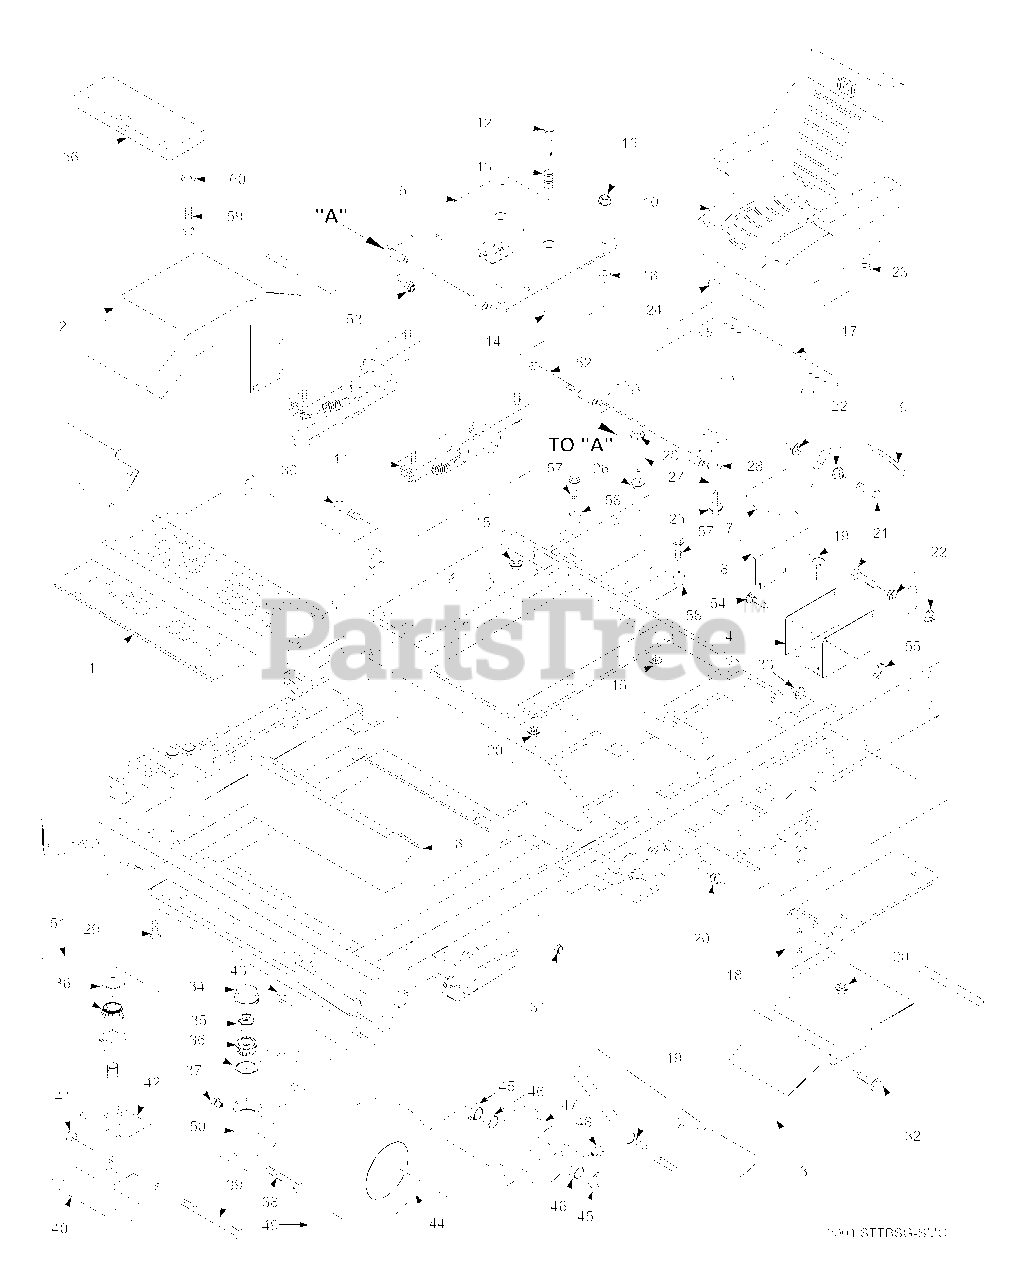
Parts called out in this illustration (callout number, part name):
1	Footplate
2	Fender, RH
3	Fender, LH
4	Box, Battery
5	Plate, Lower Seat
6	Footrest
7	Insulation, Battery Cover
8	Cover, Battery
9	Cable, Seat Stop
10	Seat
11	Track Set, Seat Adjuster
12	Pin, Spring
13	Spring, Seat
14	Spring Pin, .156 x .75"
15	Nut, Serr. Flg. 5/16-18
16	Spacer
17	Plate, Upper Seat
18	Bracket, Battery
19	Bolt, Carr. 5/16 -18 x .75"
20	Nut, Serr. Flg. 5/16-18
21	Bolt, Hex Head 1/4-20 x 1.25"
22	Nut, 1/4-20
23	Spacer
24	Spacer
25	Bolt, Hex Head 5/16-18 x 1.5"
26	Bolt, Hex Head 5/16-18 x 2.25"
27	Lock Washer 5/16"
28	Flat Washer 5/16 .375 x .875 x .083
29	Bolt, Hex Head 1/2-13 x 1.5"
30	Bolt, Hex Head 3/8-16 x 1.0"
31	Nut, Elastic Stop 3/8-16
32	Capscrew, Serr. Flng. 3/8-16 x 1.00"
33	Nut, Serr. Flng. 3/8-16
34	Cap, Grease
35	Nut, Hex Elastic Stop 1.0-14
36	Bearing w/ Race
37	Plug, 1/4-28 THD Form
38	Bolt, Hex Head 5/8-11 x 4.00"
39	Bolt, Hex Head 1/2-13 x 7.5"
40	Spacer
41	Nut, Hex Head Elastic Stop 1/2-13
42	Yoke Weldment, Caster
43	Nut, Elastic Stop 5/8-11
45	Bearing, Oilite
46	Bearing, Roller
47	Rim Assembly
48	Fitting, Grease
49	Wheel Assembly
50	Extension, Caster Wheel LH, 61"
51	Caster Wheel Assembly LH, 61" Adv.
52	Bolt, Hex Head 5/16-18 x 3.50"
53	Nut, Hex Head Elastic Stop 5/16-18
54	Bolt, Carriage 1/4-20 x 6.00"
55	Wing Nut 1/4-20 x .75"
56	Weight
57	Bolt, Hex Head 5/16-18 x 1.75"
58	Spacer
59	Bolt, Hex Head 1/2-13 x 3.5"
60	Flat Washer 1/2-.562 x .1.375 x .109
